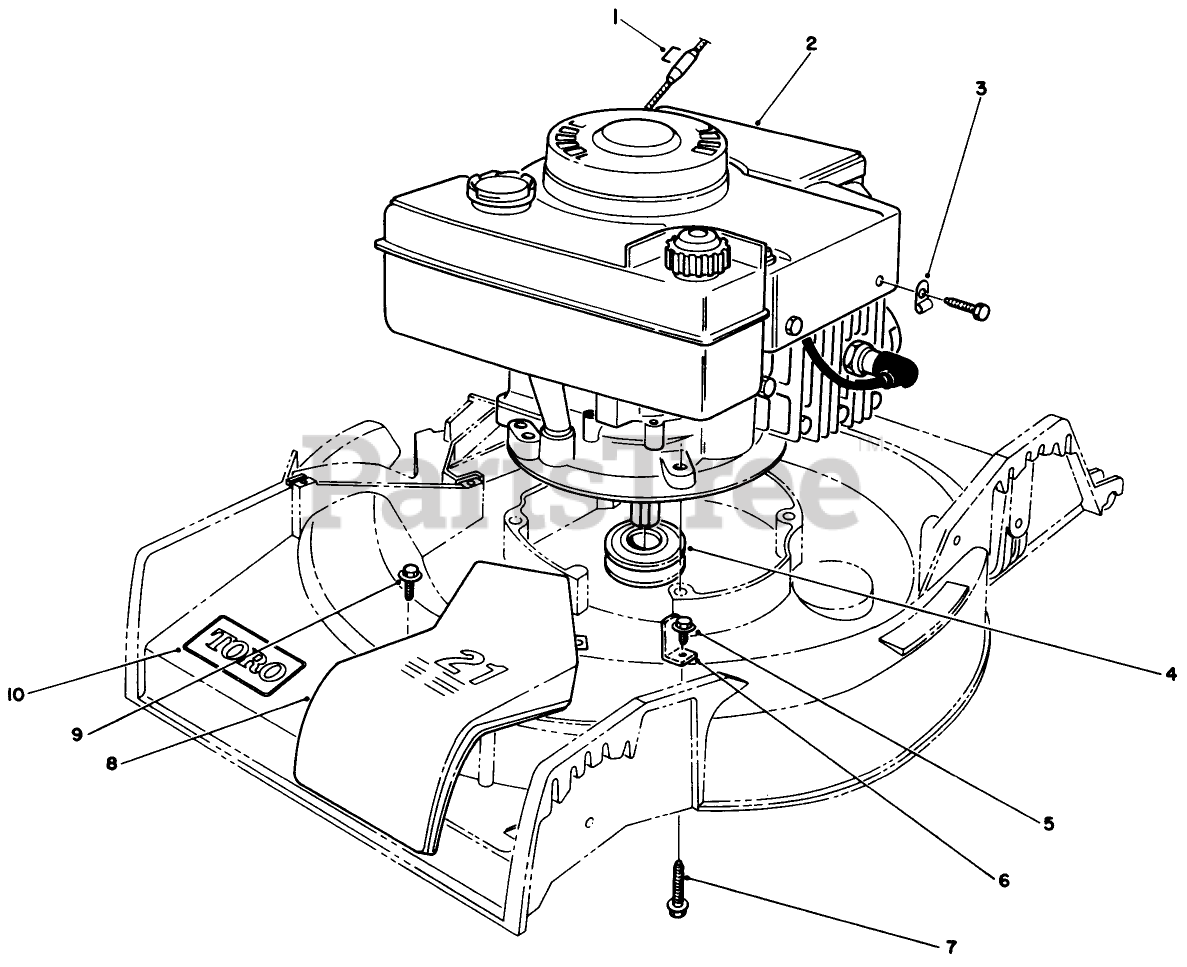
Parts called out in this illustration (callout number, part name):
1	Staple
2	Engine
4	PULLEY-DRIVER
5	SCREW-HWHTF
6	BELT GUIDE
7	3/8-16 X 2-3/4 CAPSCR
8	BELT COVER 21" S D
9	SCREW
10	DECAL
